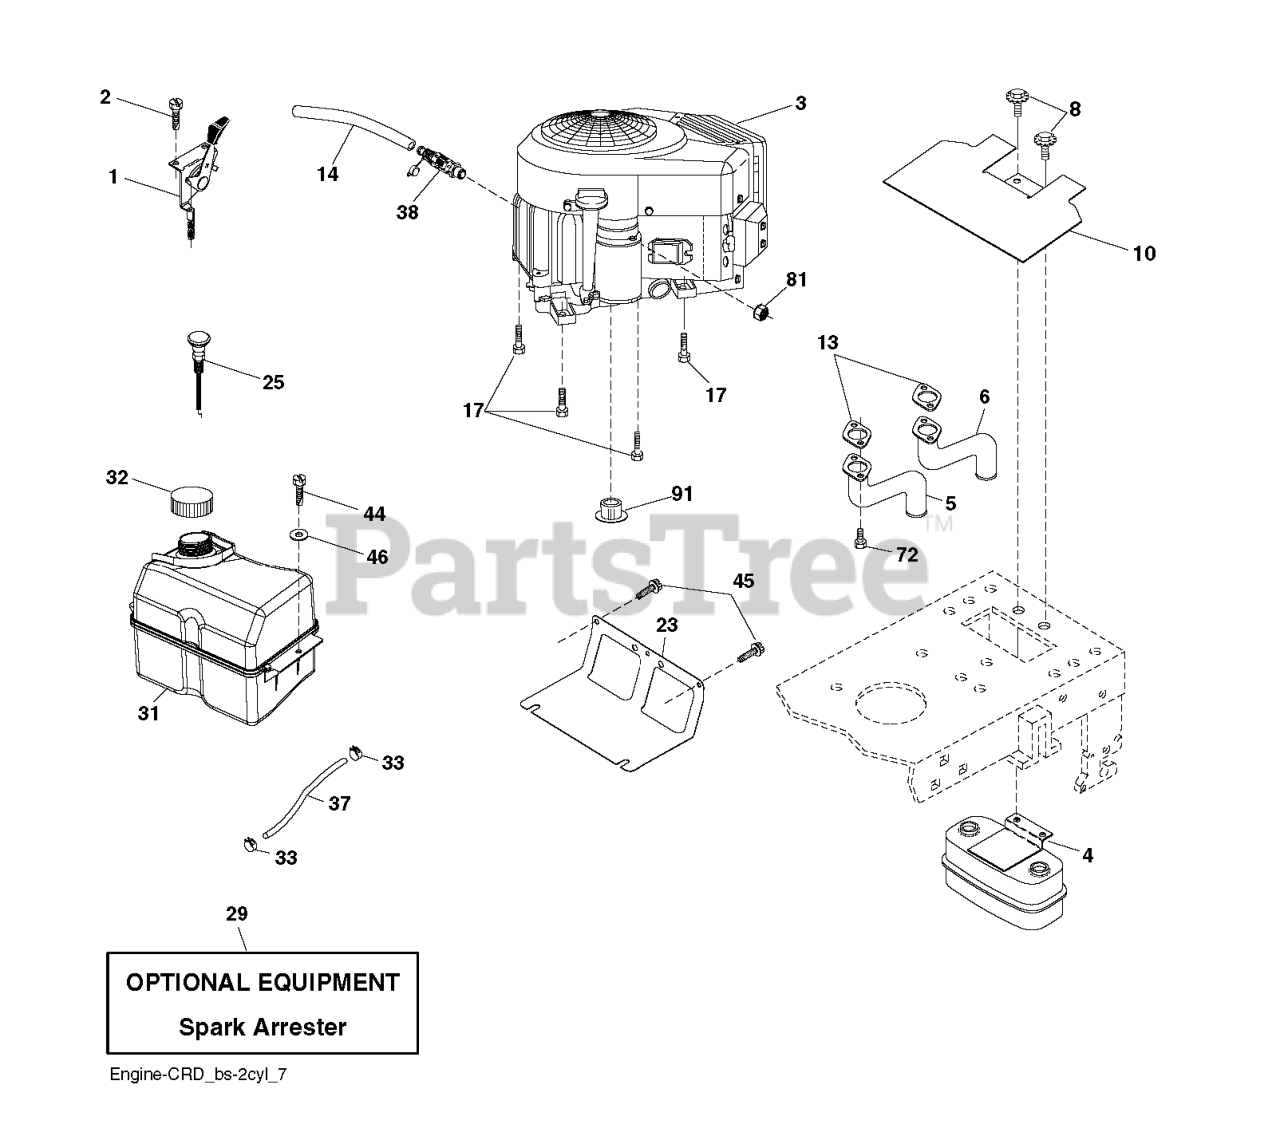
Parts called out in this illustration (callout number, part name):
1	THROTTLE CABLE
2	SCREW.#10 X 0.750.BOS
4	MUFFLER.TWIN.CYL.LOW.TONE
5	RP.EXHAUST.TUBE.LH.BS/TWIN
6	EXHAUST.TUBE.RH.BS/TWIN
8	BOLT.5/16-18UNCX3/4 W/SEMS.BLK
10	SHIELD.HEAT.MUFFLER
13	GASKET.MUFFLER
14	TUBE, DRAIN OIL ASM.
17	SCREW.3/8-16
23	SHIELD.BROWNING.DBR.GUARD
25	CONTROL.CHOKE.ERGO.PUSH-IN.BLA
29	KIT.SPARK ARRESTOR 794945 B&S
31	TANK.ASM.FUEL.FR.2.5GA.
32	CAP ASM.FUEL.2.25"FR.
33	HOSE CLAMP
37	LINE.FUEL.20
38	VALUE.OIL.DRAIN
44	SCREW HEXWSHR 1/4-20X3/4
45	SCREW, 3/8-16X3/4
72	SCREW.SOCKET.HEAD.5/16-18
81	NUT
91	BUSHING.1.375OD
